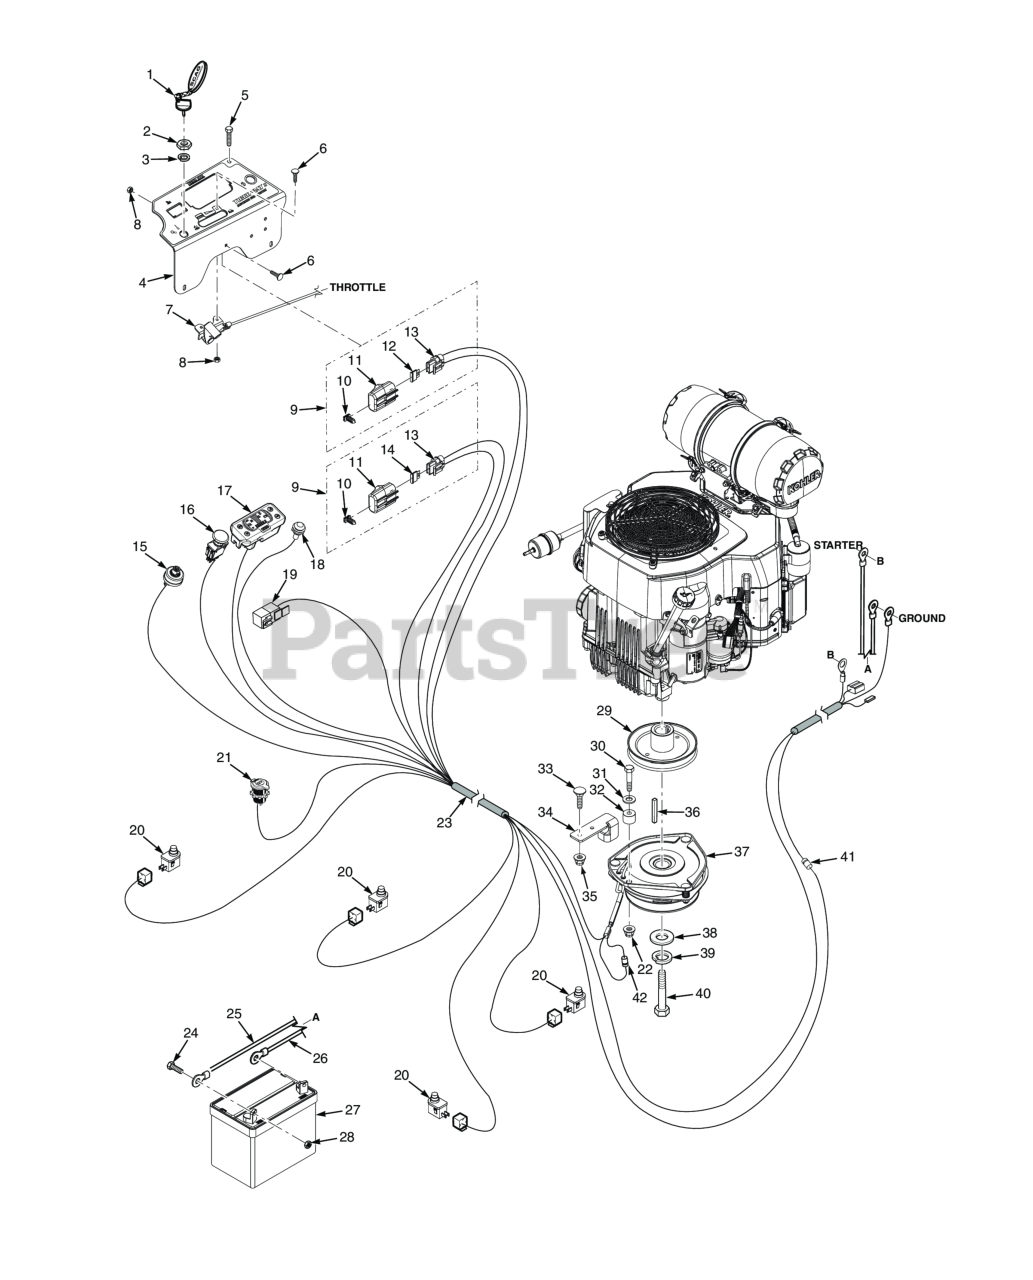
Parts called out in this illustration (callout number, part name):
1	Key, Assembly w/Fob
2	Nut, 5/8-32 Special
3	LOCK WASHER, 5/8" INTERNAL TOOTH
4	Instrument Panel w/Decal
5	CAP SCREW, 1/4-20 X 1/2" SERRATED FLANGE HEX
6	Bolt, Carriage #10-24 x 1/2"
7	Throttle Control Cable (Kawasaki FS / FX, Kohler CV)
8	Nut, Elastic Stop #10-24
9	Single Fuse Assy., Excluding Fuse
10	Clip, Fuse Holder
11	Cover, Sealed Single
12	Fuse, 5 Amp
13	Fuse Holder Assembly
14	FUSE, 20 AMP BLADE TYPE AUTOMOTIVE
15	KEY SWITCH(INCLUDES MOUNTING HARDWARE)
16	Switch, PTO - 10 Amp
17	Tiger Eye, Cluster Gauge
18	Indicator Light, Glow Plugs (Includes Mounting Hardware)
19	Relay, 12V 40 AMP Standard
20	Switch, Interlock, Normally Open
21	Power Plug, 12V
22	HEX NUT, ELASTIC STOP LOCK, 5/16-18
23	Wire Harness, STCII-CV-EFI
24	Bolt, Hex Head 1/4-20 x .5" Battery, (Not Available Through Scag)
25	Battery Cable, 25" Red
26	Battery Cable, 27" Black (35BV & 37BV-EFI) - Briggs & Stratton
27	Battery, 350 CCA
28	Nut, 1/4 - 20 Hex
29	Pulley, 5.75" Dia. - 1.125 Bore
30	Bolt, Hex Head 5/16-18 x 2-1/2" (x3) (35BV & 37BV-EFI)
31	Flatwasher, 5/16-.375 x .875 x .083 (35BV & 37BV-EFI)
32	BUSHING, UHMW
33	Bolt, 5/16-18 x .75 RHSN Carriage
34	ANTI ROTATION
35	Nut, Flange Head Elastic Stop 5/16-18
36	Key, 1/4 x 1/4 x 3-1/2"
37	Clutch w/Tag GT3.5--FE05 (61)
38	Flatwasher, 7/16-.469 x 1.75 x .25 (48, 52)
39	Lockwasher, 7/16� Spring
40	Bolt, Hex Head 7/16-20 x 2-1/4" w/Patch (Kawasaki)
41	Decal, Forward Speed Selector
42	Diode, 600V 6 Amp
